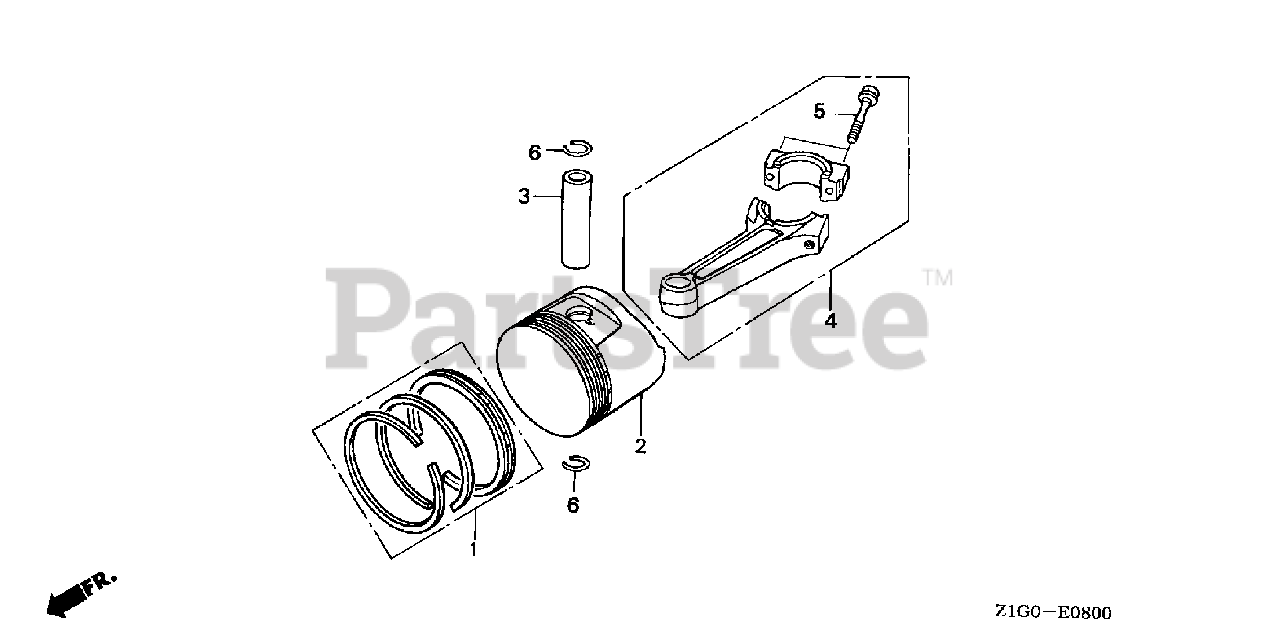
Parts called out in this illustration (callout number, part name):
1	RING SET, PISTON (STD) (RIKEN)
1	RING SET, PISTON (0.25)
1	RING SET, PISTON (0.50)
1	RING SET, PISTON (0.75)
2	PISTON (STD)
2	PISTON (0.25)
2	PISTON (0.50)
2	PISTON (0.75)
3	PIN, PISTON
4	ROD ASSY., CONNECTING (STD)
4	ROD ASSY., CONNECTING
5	BOLT, CONNECTING ROD
6	CLIP, PISTON PIN (20MM)
